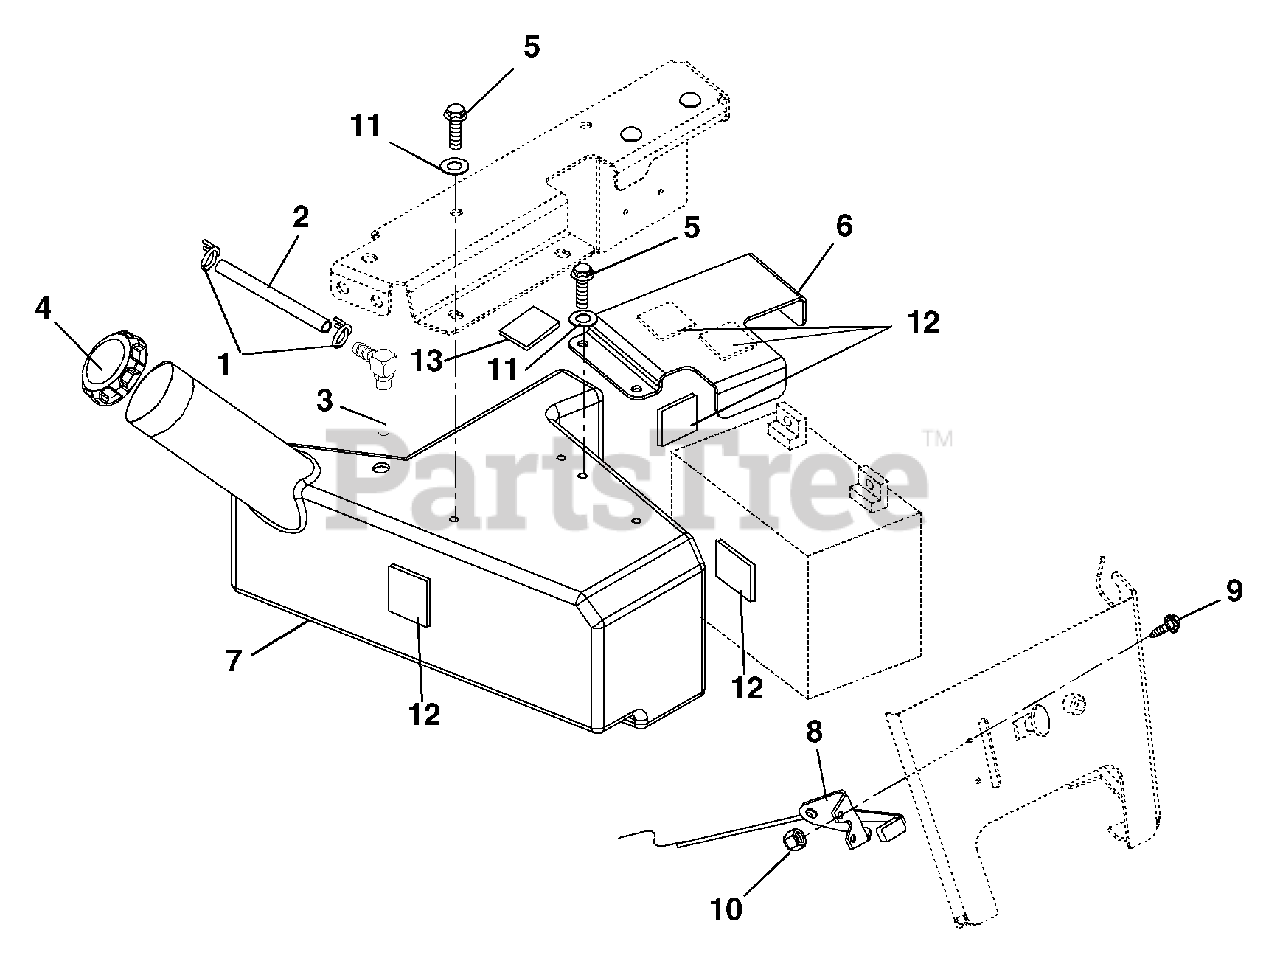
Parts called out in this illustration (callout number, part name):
1	CLAMP-HOSE WIRE .490/.510X.116
2	GAS LINE-BULK 1/4" I.D.
3	TANK FITTING
4	FUEL CAP
5	BLT-SERHFWH .25-20X.75 YWZC
6	BRACKET-BATTERY
7	TANK-FUEL
8	THROTTLE CABLE
9	@SCR-MCH 10-24X.50 HWH YWZC
10	@NUT-LK-NYL 10-24 W/INSRT YWZC
11	@WSHR-LK .31X.078 REG YWZC
12	PAD, FOAM
13	VHB TAPE 4941F
